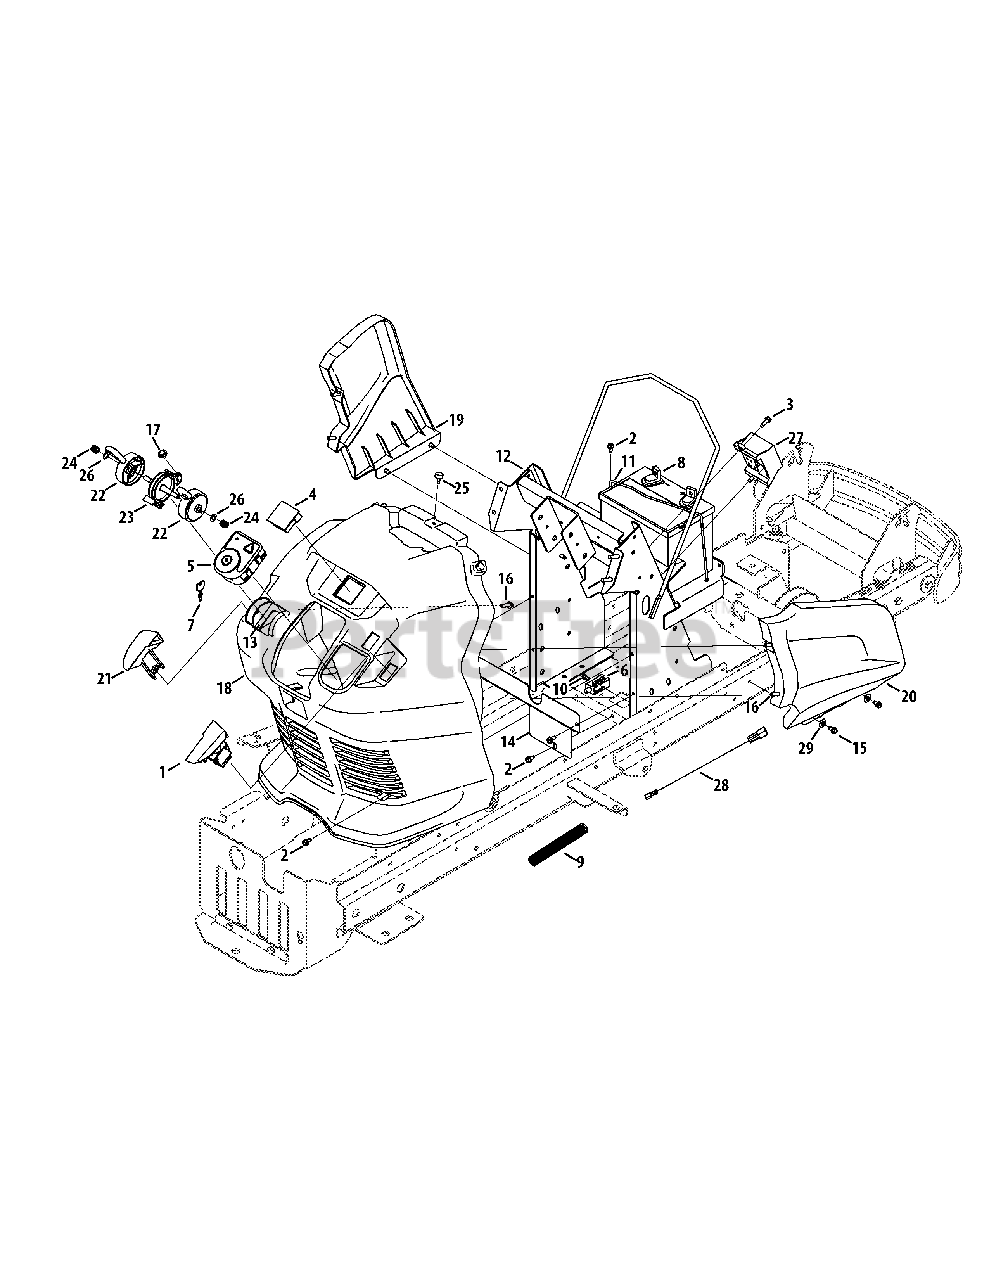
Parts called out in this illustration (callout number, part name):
1	PTO Lever
2	Hex Washer Screw, 1/4-20 x .500
3	Hex Washer Screw, 1/4-20 x .750
4	Hour/Service Minder Indicator Meter
5	Key Switch
6	Interlock Switch
7	Key Assembly
10	Shoulder Screw, #10-32 x .500
11	Battery Strap
12	Steering/Battery/Dash Frame Assy.
13	Throttle Control Mount Bracket
14	Engine Air Upper Shield
15	Hex Washer Screw, 5/16-18 x .750
16	Hex Washer Screw, 5/16-14 x 1.00
17	Hex Washer Screw, #10-16 x .375
18	Dash
19	LH Dash Panel
20	RH Dash Panel
21	Cruise/Brake Lever
22	Choke/Throttle Control
23	Choke/Throttle Index Disc
24	Compression Spring, .50 x .50
25	Bumper, .62 x .3
26	Flat Washer, .344 x .620 x .033
27	Wire Harness
28	Reverse Jumper Harness
29	Flat Washer, .406 x .875 x .059
